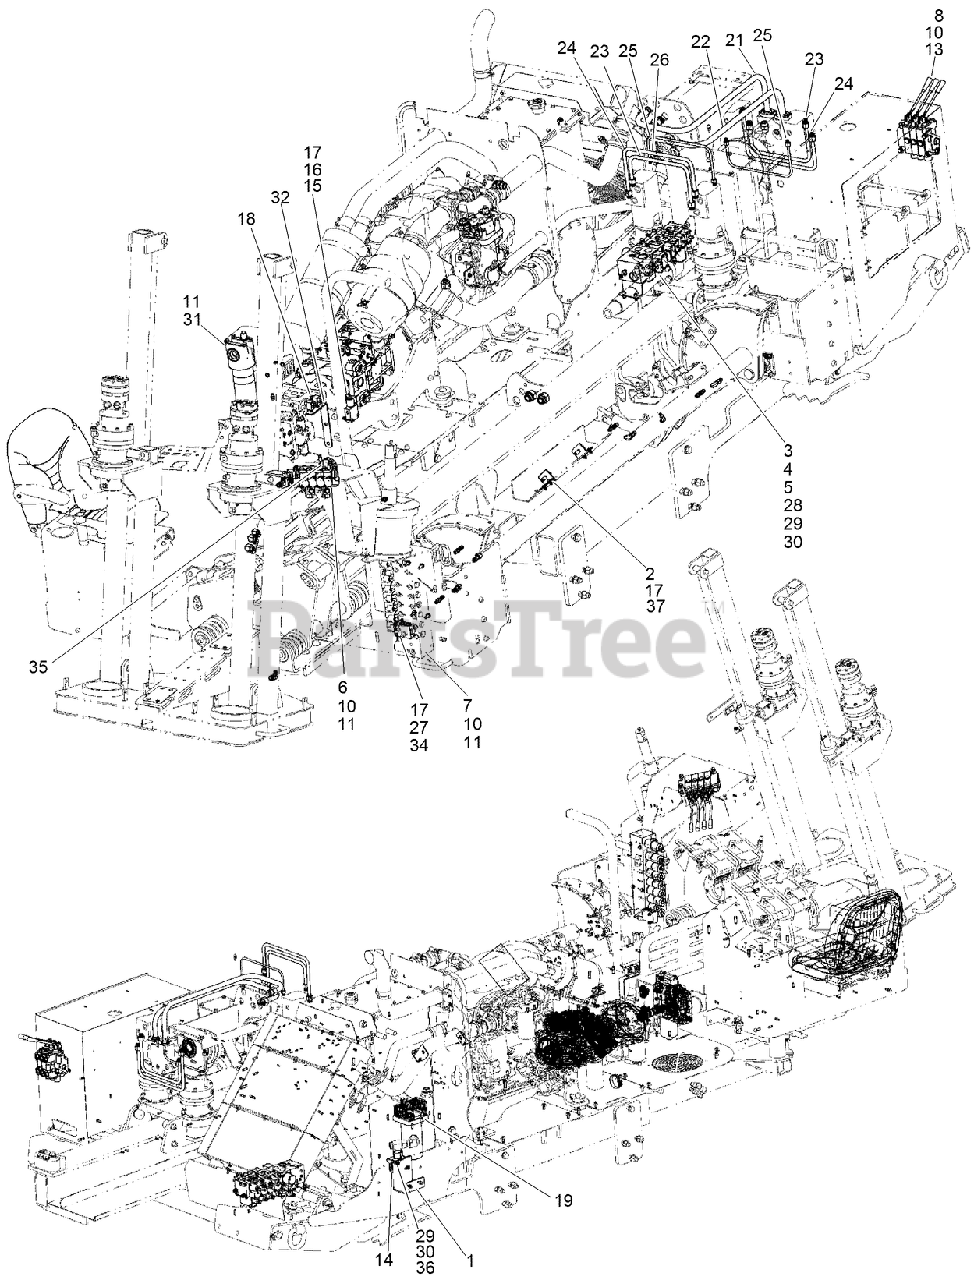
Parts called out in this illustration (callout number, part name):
1	PLATE - Mount, Thermal Bypass
2	PLATE - Mount
3	BRACKET-FRONT, 5-SECTION VALVE
4	5-SECTION HYD VALVE ASM
5	BRACKET-REAR, 5-SECTION VALVE
6	4 SPOOL HYD VALVE ASM
7	9 SECTION HYD VALVE ASM
8	3 SPOOL HYD VALVE ASM
10	WASHER-FLAT
11	SCREW-HH
13	BOLT
14	VALVE-THERMOSTAT
15	VALVE - Dir, Cart, 3W2P, SOL, 12VDC
16	SCREW, METRIC FLANGE w/BODY - M6 x 50
17	NUT, METRIC FLANGE PREVAILING - M6 Zinc
18	VALVE-SHUTTLE, LOAD
19	FILTER-HYD, RETURN
21	TUBE-HYD, ROTARY A (BULKHEAD TO MOTOR)
22	TUBE-HYD, ROTARY B (BULKHEAD TO MOTOR)
23	TUBE-HYD, 5/8 IN (MOTOR TO MOTOR)
24	TUBE-HYD, 5/8 IN (MOTOR TO MOTOR)
25	TUBE-HYD, 3/8 IN (CASE DRAIN MTR TO MTR)
26	CLAMP - Hose, Type M # 12
27	HYD FLOW DIVIDER VALVE ASM
28	SCREW-FLANGE
29	SCREW-HH
30	NUT-TORQUE, PREVAILING
31	FILTER-HYD, HIGH PRESSURE
32	PLATE - Mount, Shuttle Valve
34	SCREW-FLANGE, METRIC
35	CLAMP, T-BOLT - Spring Load, 2.75 Min - 3.06 Max
36	SCREW-FLANGE
37	SCREW-HHF
